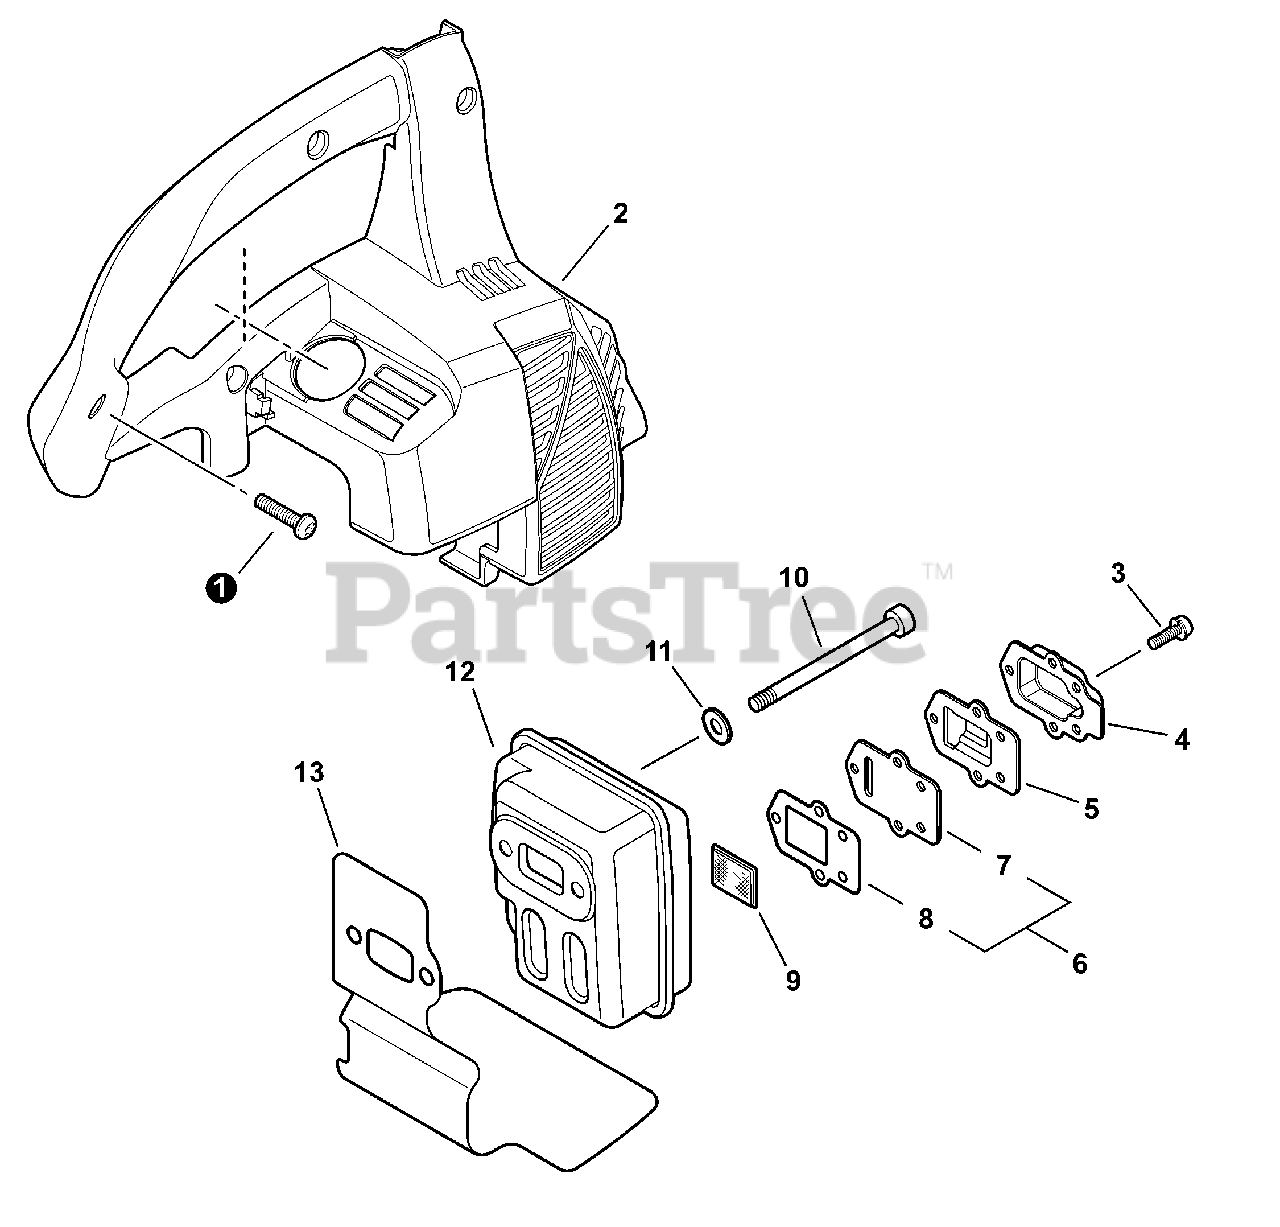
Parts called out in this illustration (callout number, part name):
1	BOLT, TORX 5×20
2	COVER, ENGINE
3	BOLT, TORX 4×8
4	OUTLET, EXHAUST
5	GUIDE, EXHAUST
6	GASKET KIT, EXHAUST
7	GUIDE, EXHAUST
8	GASKET, EXHAUST
9	SCREEN, SPARK ARRESTER
11	WASHER 5.5×12×0.8
12	MUFFLER
13	HEAT SHIELD, EXHAUST
